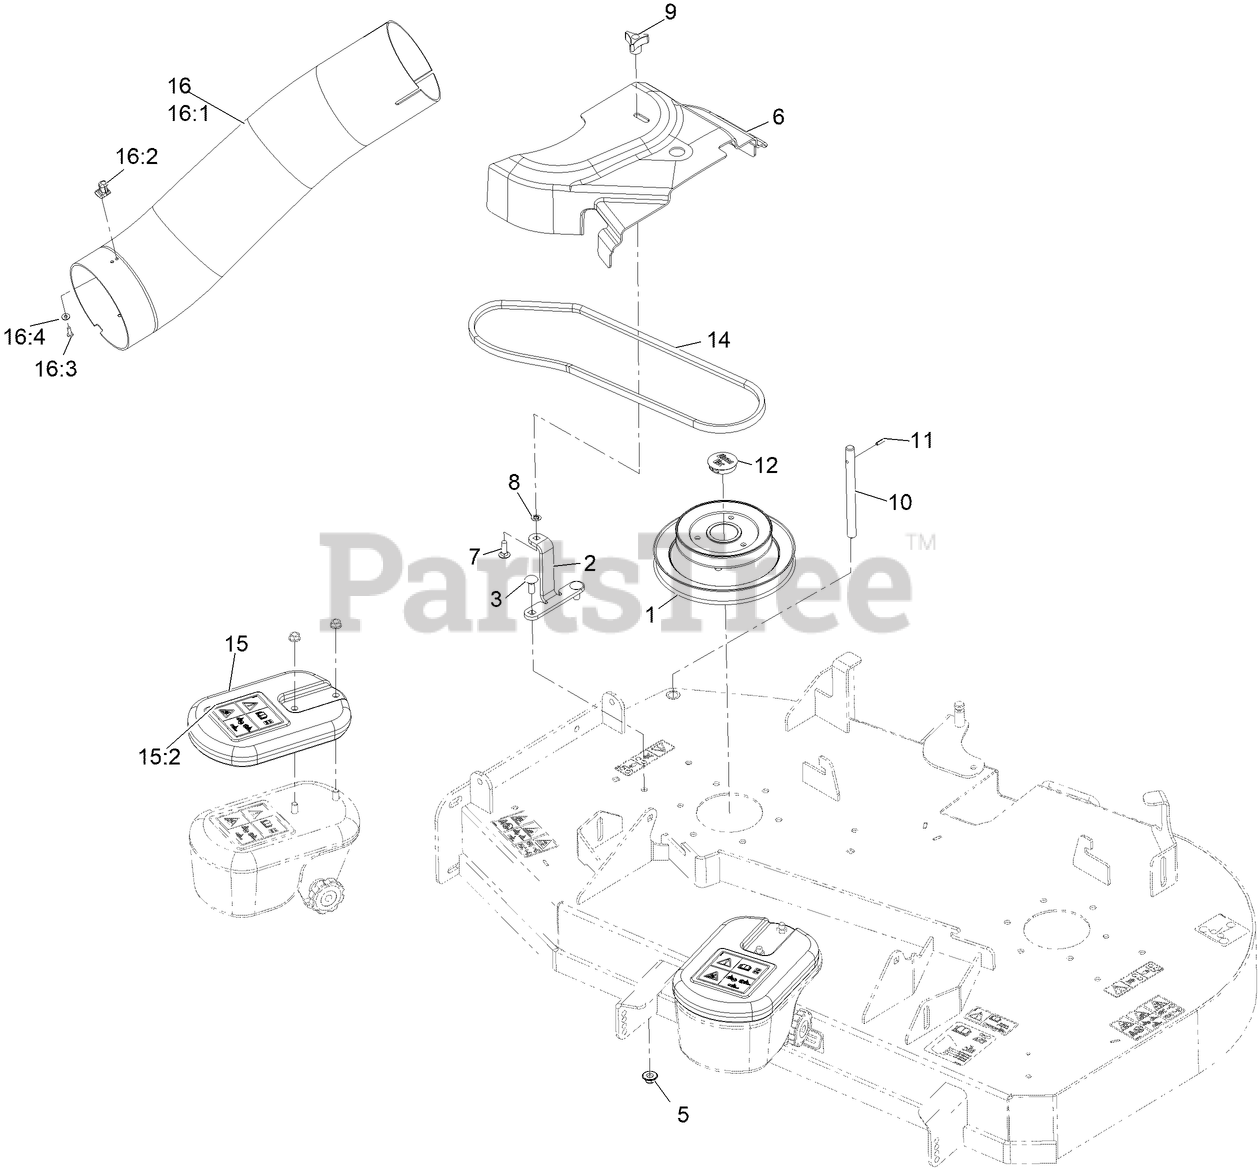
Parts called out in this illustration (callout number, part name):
1	Jackshaft-Uv Drive 482B Splined
2	Bracket-Cover
3	BOLT-CARR
5	Nut-Nyloc 3/8-16 Flg
6	COVER-BELT-UV
7	BOLT-CARR
8	RING-RETAINING, BOLT
9	KNOB-3 PRONG
10	SHAFT-CATCHER, GRASS
11	PIN-ROLL
12	PLUG, BLACK NYLON 1.75
14	BELT-V
15:2	DECAL-WARNING, TRACTION
16	LOWER TUBE ASM
16:1	Tube-Long, Lower
16:2	LATCH-KEEPER
16:3	SCREW-PPH
16:4	WASHER-FLAT
